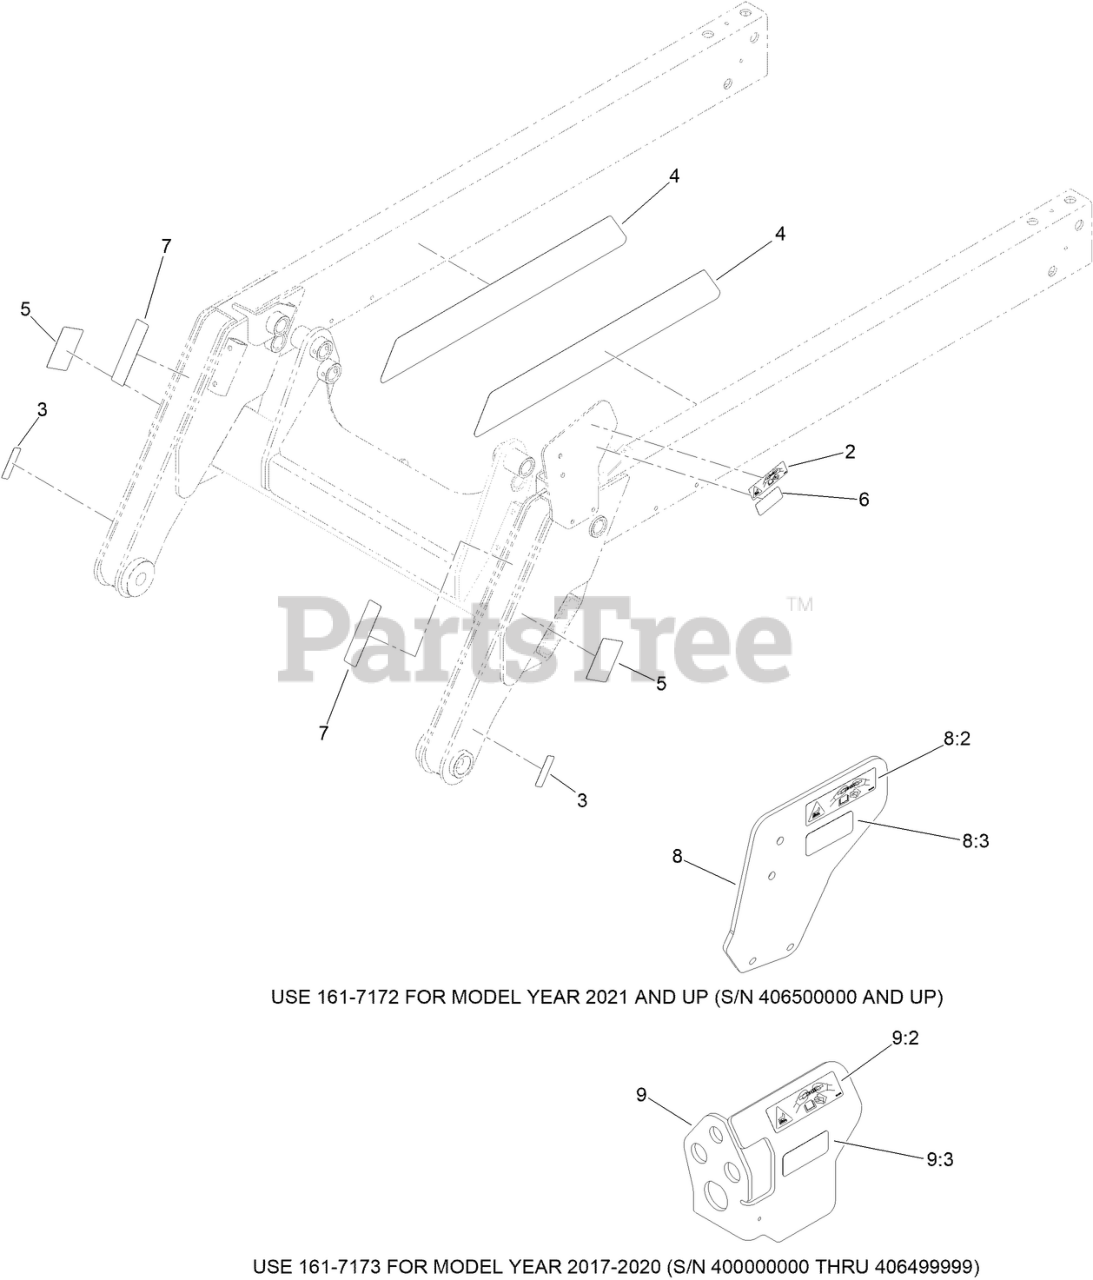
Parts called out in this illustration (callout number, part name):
2	DECAL-CAUTION
3	DECAL-WARNING, PINCH POINT
4	DECAL-EXTENSION
5	DECAL-WARNING, BUCKET
6	DECAL-WARNING, HYD PRESSURE
7	TAPE-REFLECTIVE
8	PLATE-MOUNT QC
8:2	DECAL-CAUTION
8:3	DECAL-WARNING, HYD PRESSURE
9	MOUNT-PLATE QD
9:2	DECAL-CAUTION
9:3	DECAL-WARNING, HYD PRESSURE
